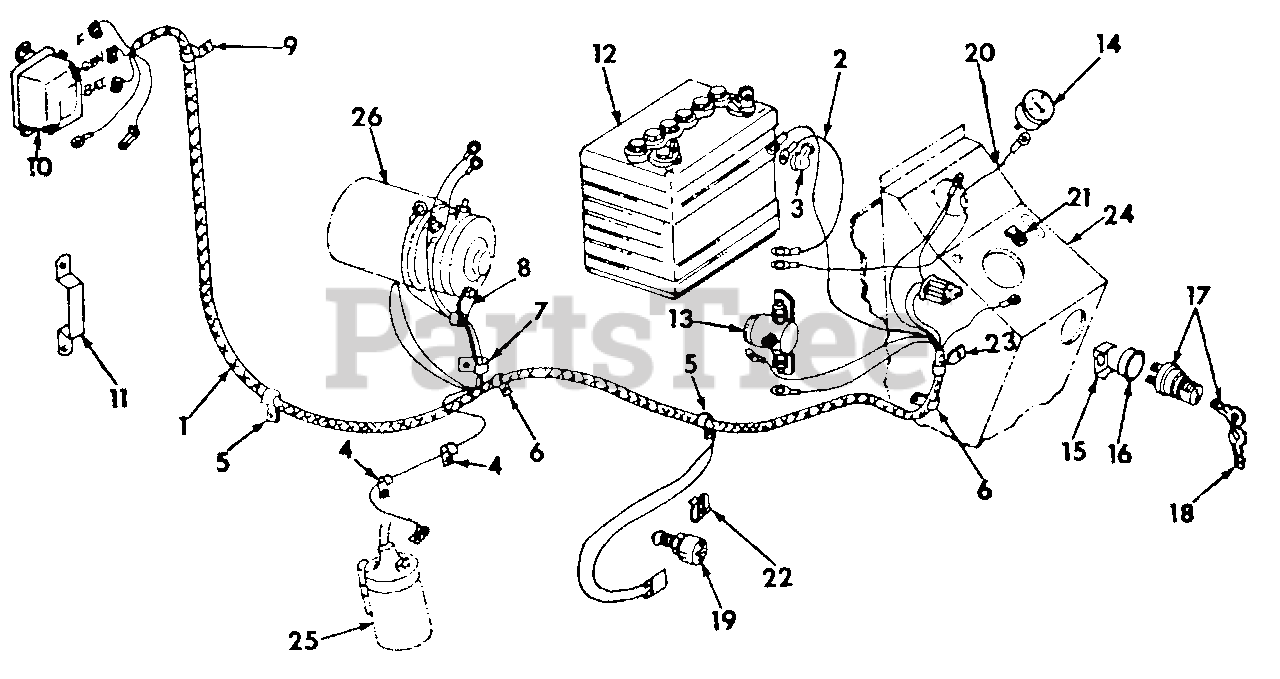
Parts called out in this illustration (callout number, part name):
1	Harness Assy, Cable
2	Cable Assy, Battery to Magnetic Switch
3	Cover, Battery Terminal
4	Clip, Ignition Cable
5	Clip, Cable Harness
6	Clip, Cable Harness, Long
7	Clip, Generator Cable
8	Clip, Cable Harness
9	Clip, Cable Harness
10	Regulator, Voltage
11	Bracket, Voltage Regulator
12	Battery, Prestolite 9948X, 12 Volt
13	Switch Assy, Magnetic
14	Indicator Assy, Charge
15	Retainer, Ignition Switch
16	Socket, Ignition Switch
17	Switch Assy, Battery Ignition
18	Key, Switch
19	Switch Assy, Safety Start
20	Cable Assy, Charge Indicator
21	Not used in this application
22	Clip, Safety Starting Switch Cable Snap On
23	Clip, Cable Harness
24	Pedestal Assy
25	Coil, Ignition
26	Motor Assy, Generator
